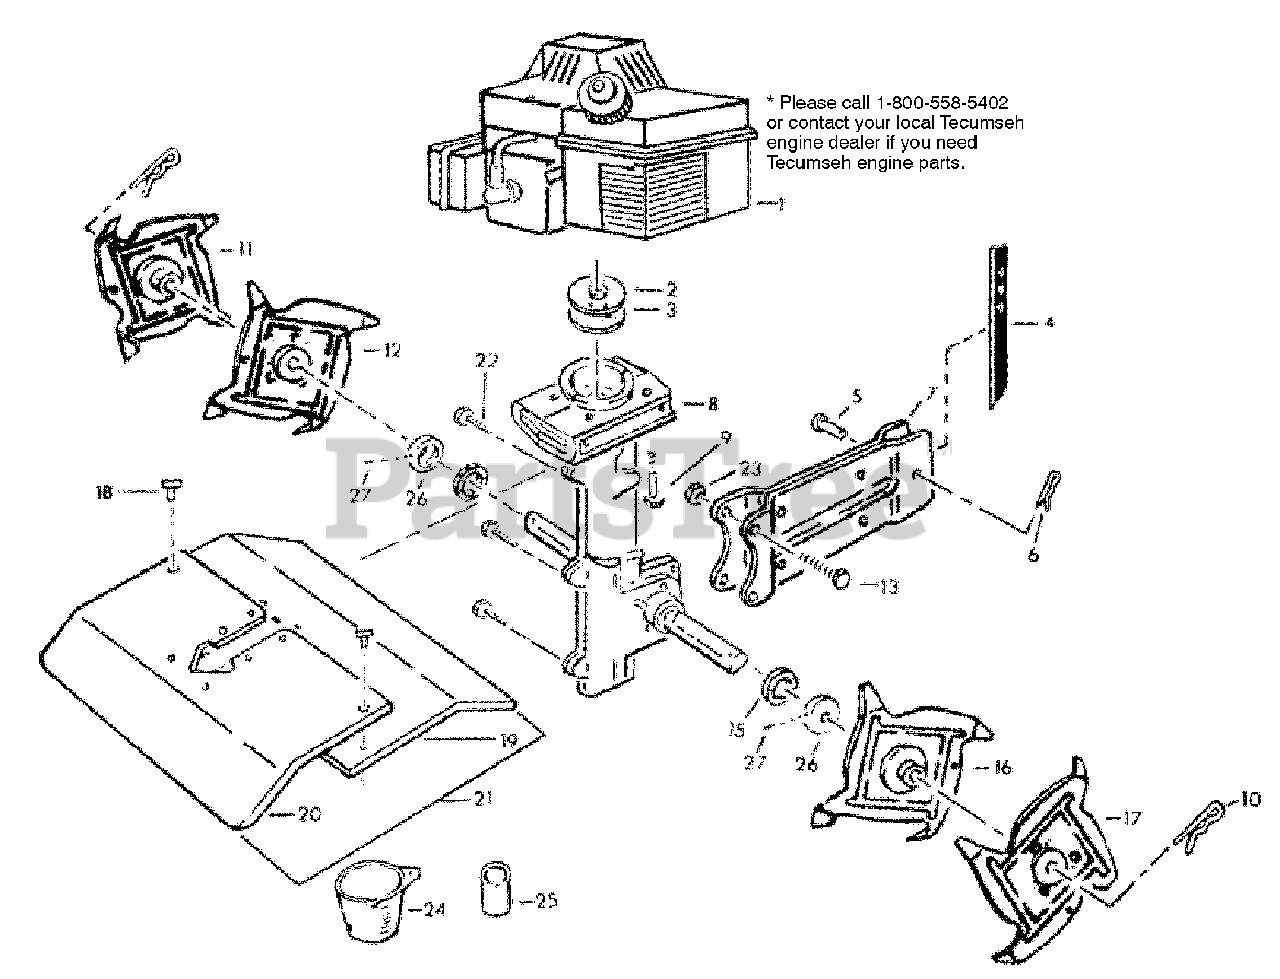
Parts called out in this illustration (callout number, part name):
1	Engine
2	Clutch Assy
3	Spring, Clutch
4	Drag Stake
5	Pin, Clevis 5/16 x 7/8
7	Bracket Assembly
8	Transmission Assembly, Complete
9	Screw, Whizz Loc, 1/4-20 x 2
11	Tine & Hub, R.H. Outbrd
12	Tine & Hub, R.H. Inbrd
13	Screw, 1/4 - 20 x 1"
16	Tine & Hub, L.H. Inbrd
17	Tine & Hub, L.H. Outbrd
22	Screw, 1/4 - 20 x 7/8, Thrd. From
23	Nut, 1/4 - 20
24	Fuel Mix Cup
25	Tine Spacers
26	Dirt Cap, Silver Metal
27	Set Screw, #10 - 32 x 1/4, Metal Dirt Cap
